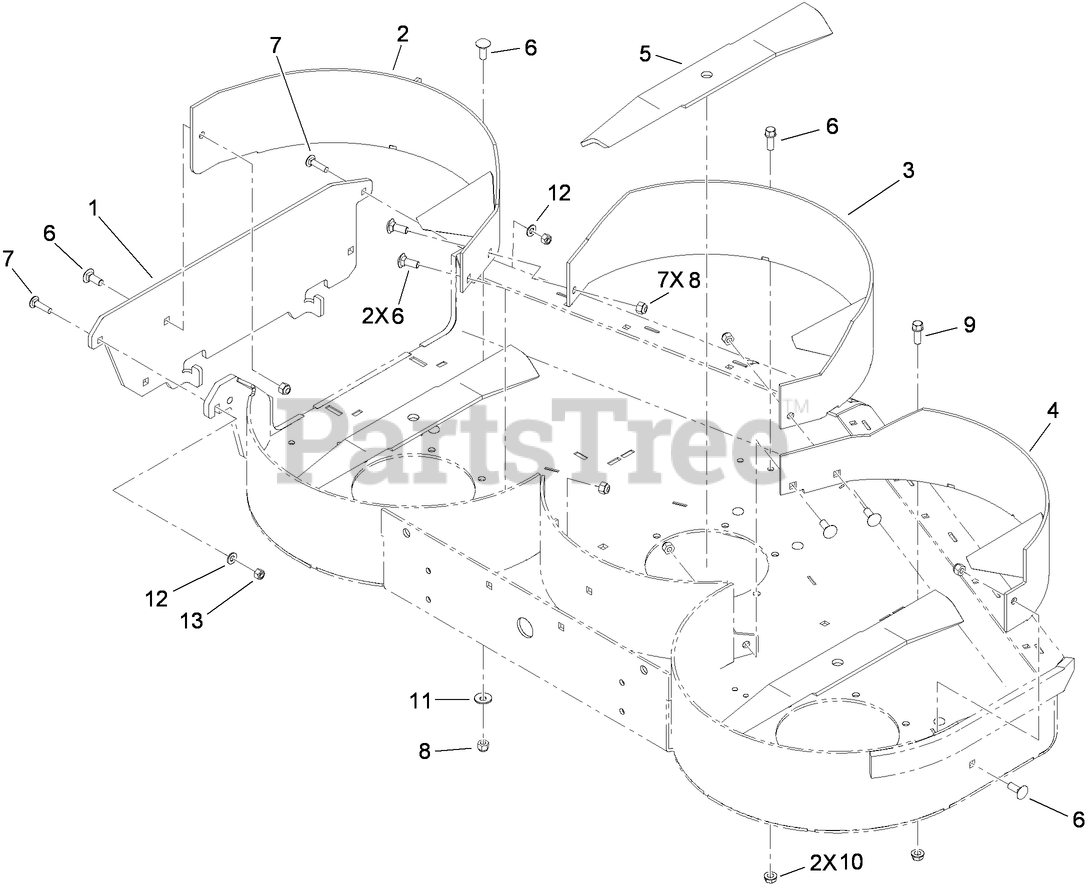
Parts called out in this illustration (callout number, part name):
1	PLATE-COVER, DISCHARGE
2	RH BAFFLE ASM
3	CENTER BAFFLE ASM
4	LH BAFFLE ASM
5	BLADE-RECYCLER
6	BOLT-CARR
7	SCREW-CARR
8	NUT-LOCK, NI
9	SCREW-HWH
10	NUT-HHF, WHIZ
11	WASHER-BELLEVILLE
12	WASHER-PLAIN
13	NUT-LOCK, NI
